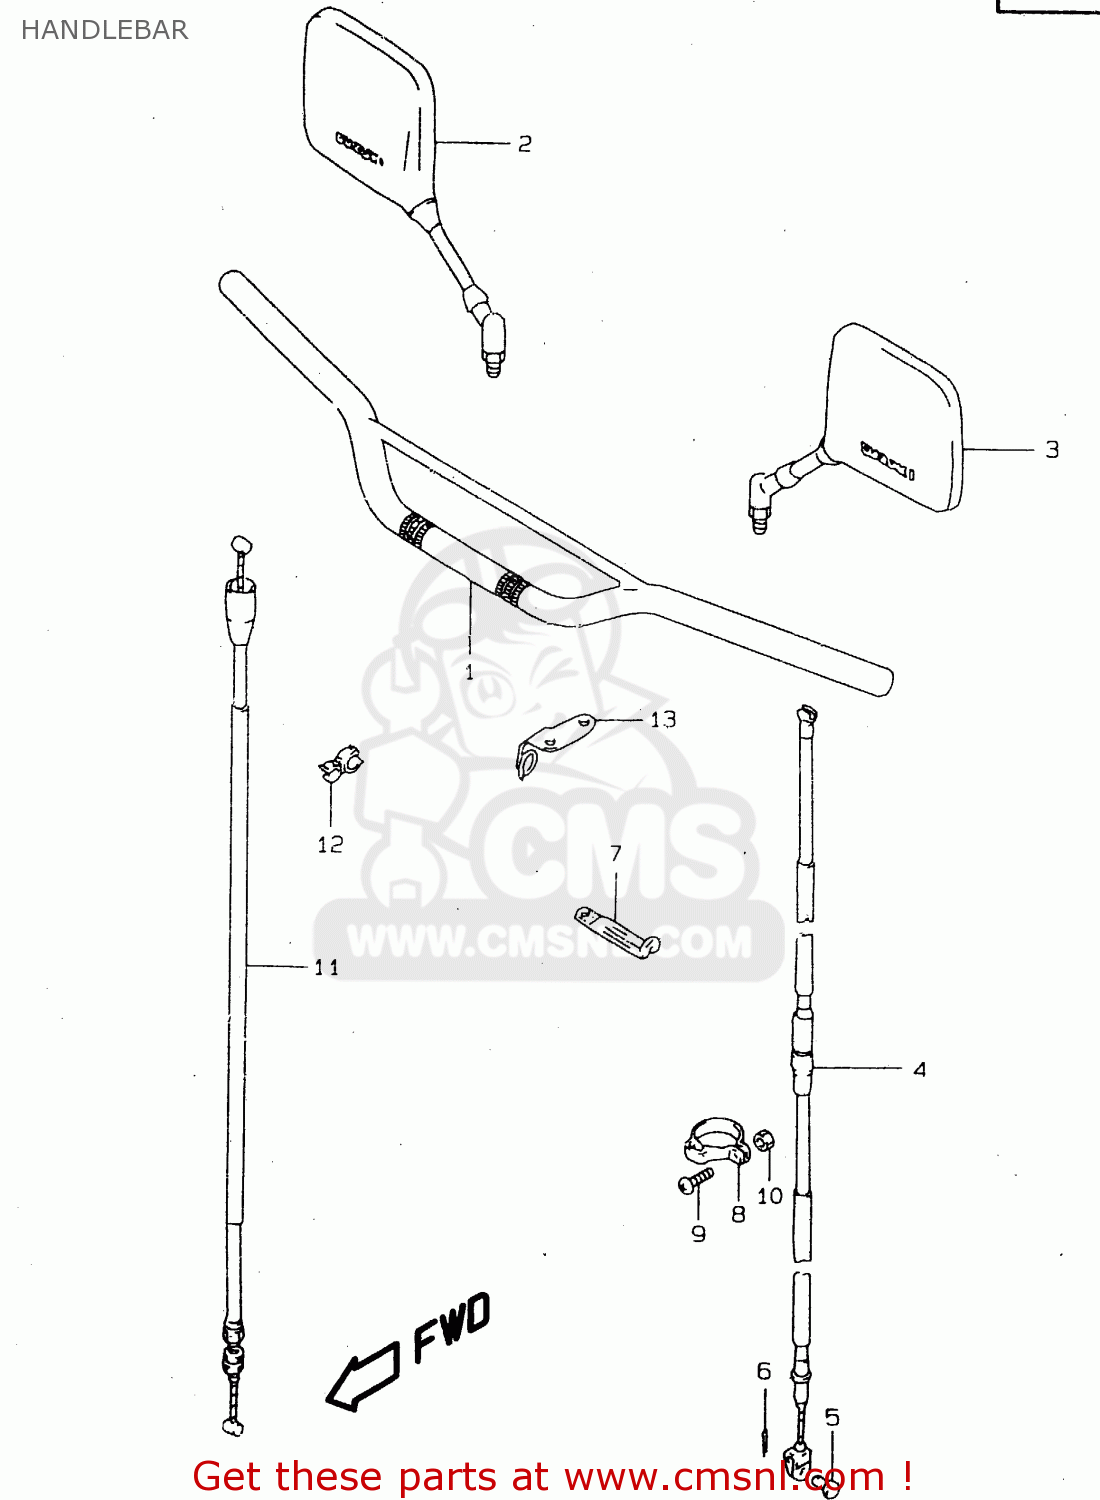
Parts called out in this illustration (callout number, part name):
1	HANDLEBAR(BLACK)
2	MIRROR ASSEMBLY,REAR VIEW
3	MIRROR ASSEMBLY,REAR VIEW
4	CABLE ASSY,CLUTCH
5	PIN(L:13)
6	PIN
7	CLAMP(L:235)
8	CLAMP,CABLE
9	SCREW
10	NUT
11	CABLE ASSY,THROTTLE
12	CLAMP
13	GUIDE,CABLE
